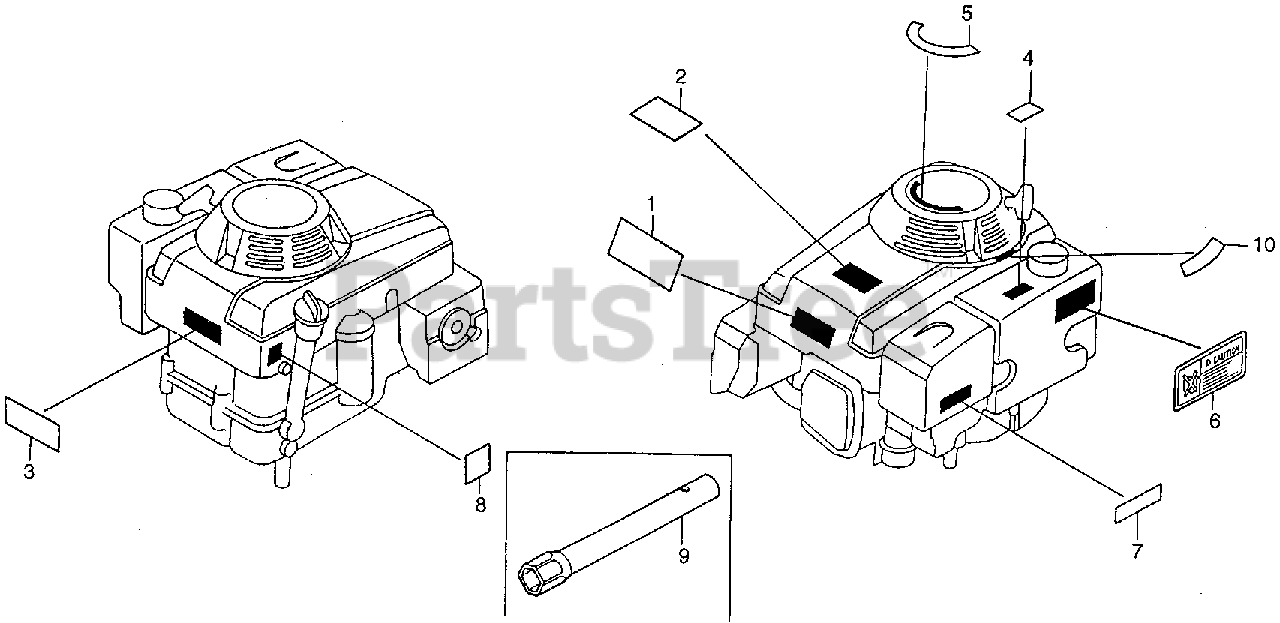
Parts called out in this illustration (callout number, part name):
2	MARK, TOP COVER (OIL ALERT)
2	MARK, TOP COVER
3	LABEL, EMBLEM (Honda Code 3132255). (ENGLISH/FRENCH/GERMAN)
4	LABEL, FUEL CAUTION (ENGLISH)
5	MARK, EASY START (ENGLISH)
7	MARK, AIR CLEANER CAUTION
8	MARK, OIL CAUTION
9	WRENCH, BOX (P21)
